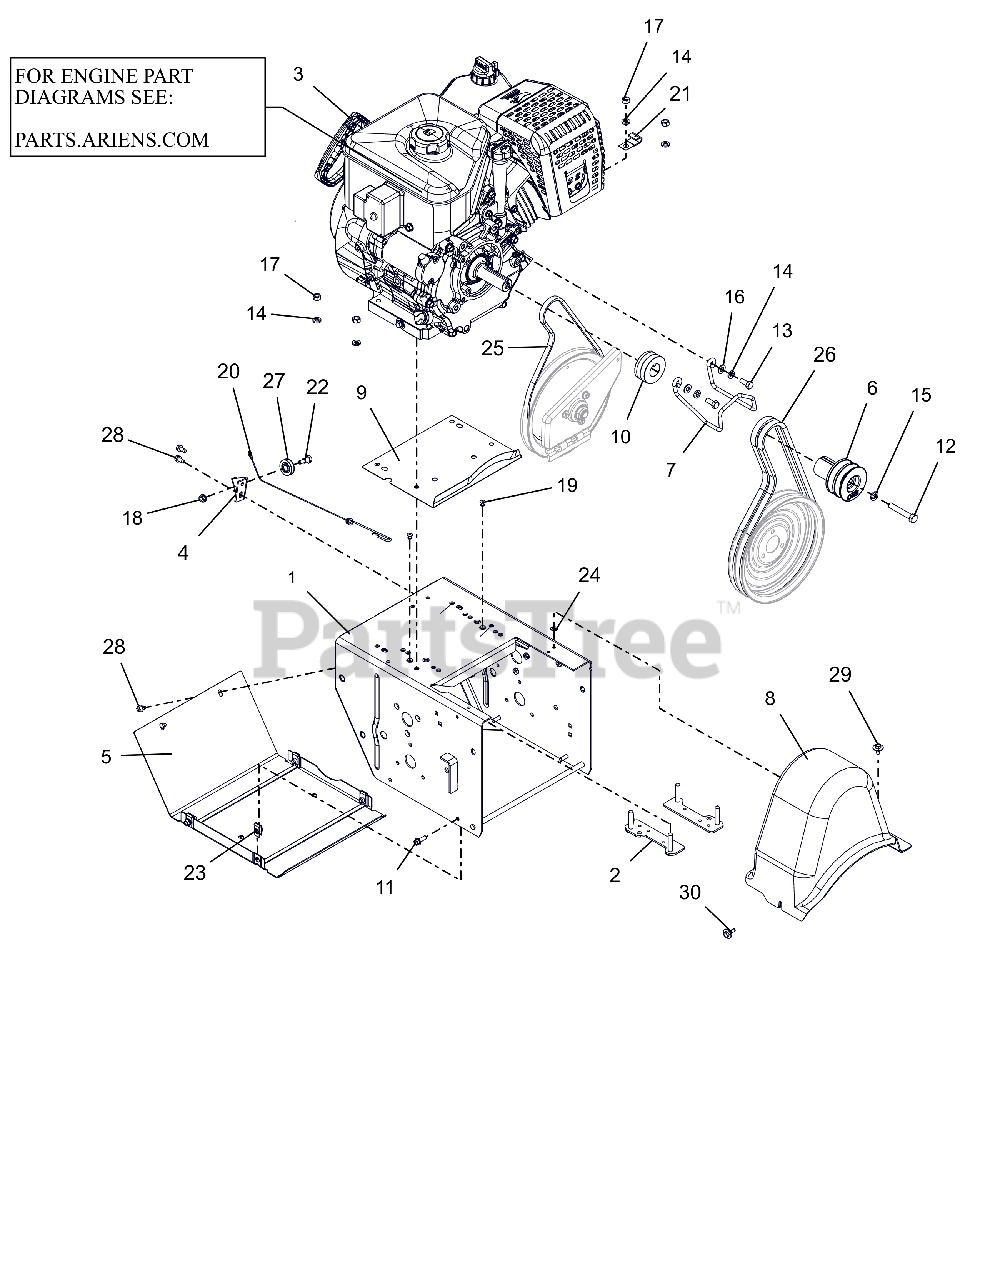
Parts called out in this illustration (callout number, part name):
1	FRAME, MAIN-DELUXE(WELDMENT)
2	STRAP, BOLT-LARGE
3	ENGINE, AX414 GEN3 120V/60W
4	BRACKET, CABLE PULLEY
5	COVER, BOTTOM
6	SHEAVE,ATTACHMENT-SHO 2 GRV
7	FINGER, BELT
8	COVER, BELT-LARGE
9	BAFFLE, WATER - LARGE BLOCK
10	SHEAVE, DRIVE
11	BLT, HWH .25-20X.75 G5 ZCC
12	BLT, HEX .38-24X2.25 G5 ZCC
13	BLT, HEX .31-24X.750 G5 ZCC
14	WSHR, LK-HVY .312X.097 ZCC
15	WSHR,LK-REG .375X.094 ZCC
16	WSHR,FLT .344X.688X.065 ZCC
17	NUT, HEX .312-18 ZCC
18	NUT-LK-TOP-FLG .250-20 GF ZCC
19	RVT, POP .1875 ZCC
20	CABLE, LOWER TRACTION,SS & PRO
21	J-CLAMP
22	BOLT, SHLDR-.375X.375X.25-20
23	NUT-RTNR .25-20X.56
24	NUT-PUSH .25X.50 O.D.
25	V-BELT, 3L-WRAPPED
26	V-BELT, HA-RAW EDGE (SET)
27	PULLEY, CABLE
28	SCR-TAP .25-20X.50 HWH ZCC
29	SCR, TAP .25-20X.50 LG HWH ZCC
30	SCR-TAP .25-20X.5 CAPTIVE
